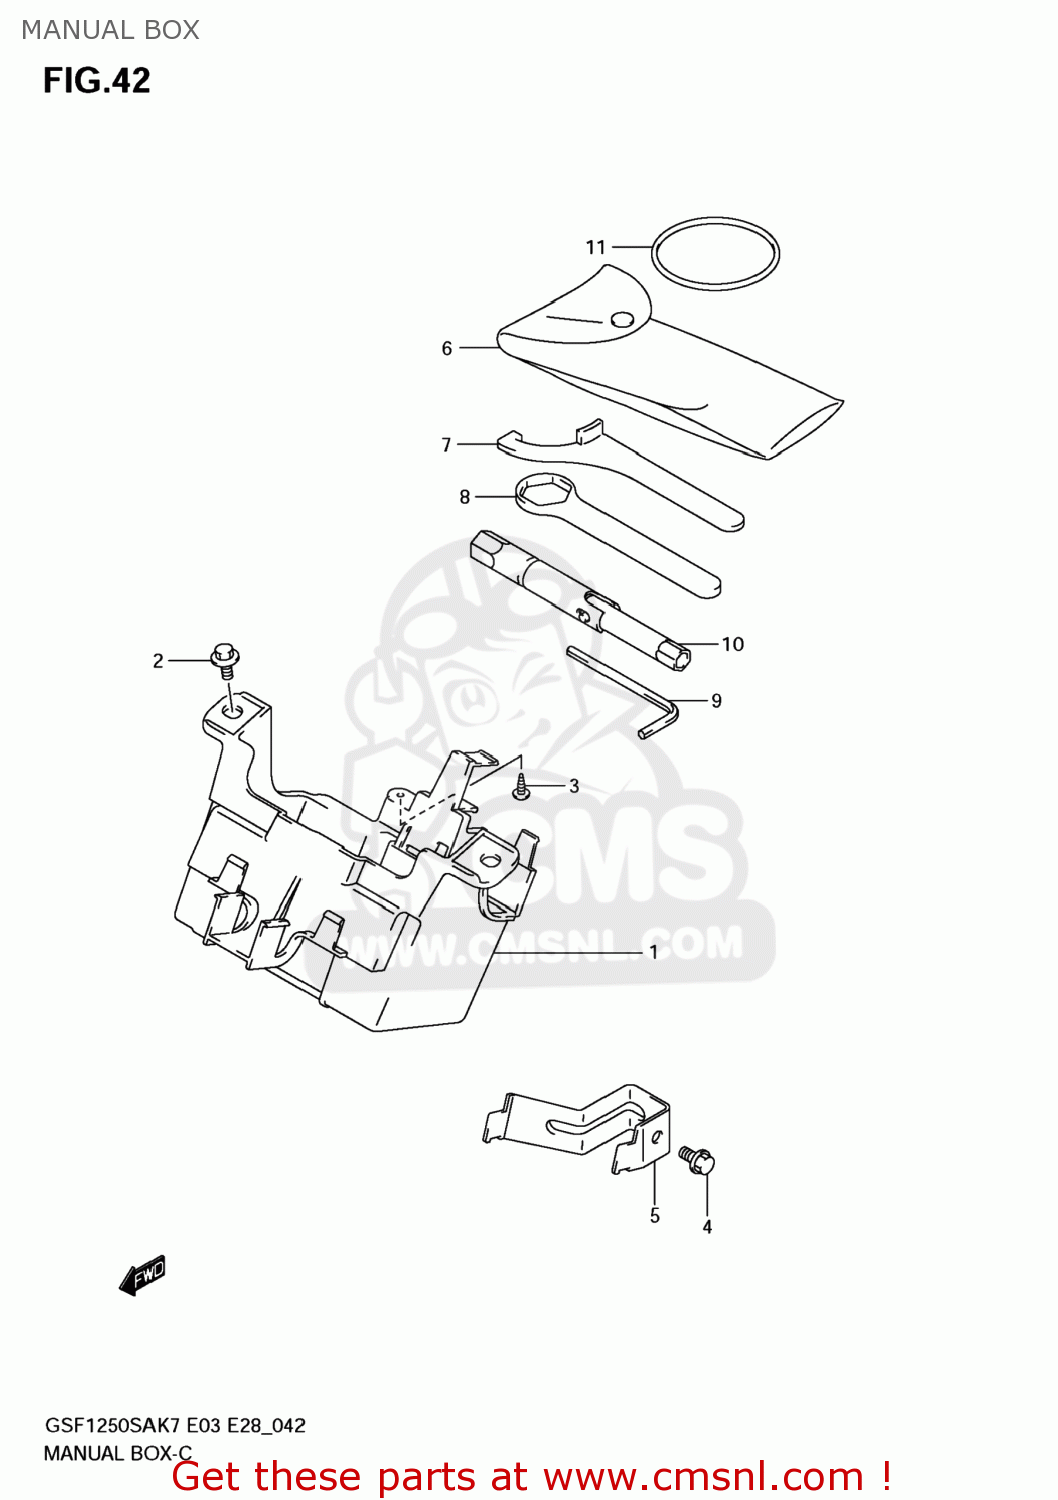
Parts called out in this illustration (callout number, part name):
1	HOLDER,BATTERY
2	BOLT
3	SCREW
4	BOLT
5	PLATE,FUSE BOX
6	TOOL ASSY
7	CLAMP
8	RING SPANNER(36)
9	HEXAGON SPANNER,5
10	SPARK PLUG WRENCH
11	O RING(D:3.5,ID:61)
